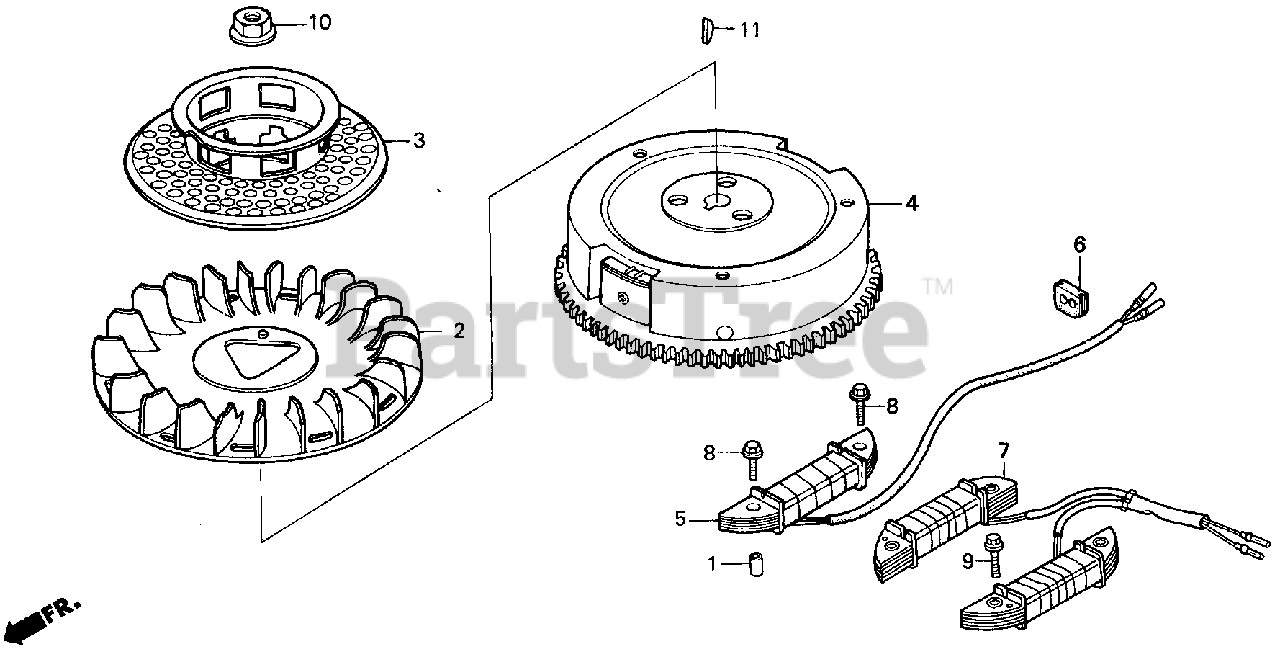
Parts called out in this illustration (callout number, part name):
1	COLLAR, EXTENSION
2	FAN, COOLING
4	FLYWHEEL (SEL-4POLE)
5	COIL ASSY., CHARGE (2A-3A)
5	COIL ASSY., CHARGE
6	GROMMET, WIRE
8	BOLT, FLANGE (6X28)
8	BOLT, FLANGE (6X25)
10	NUT, SPECIAL (16MM)
11	KEY, SPECIAL WOODRUFF (25X18)
